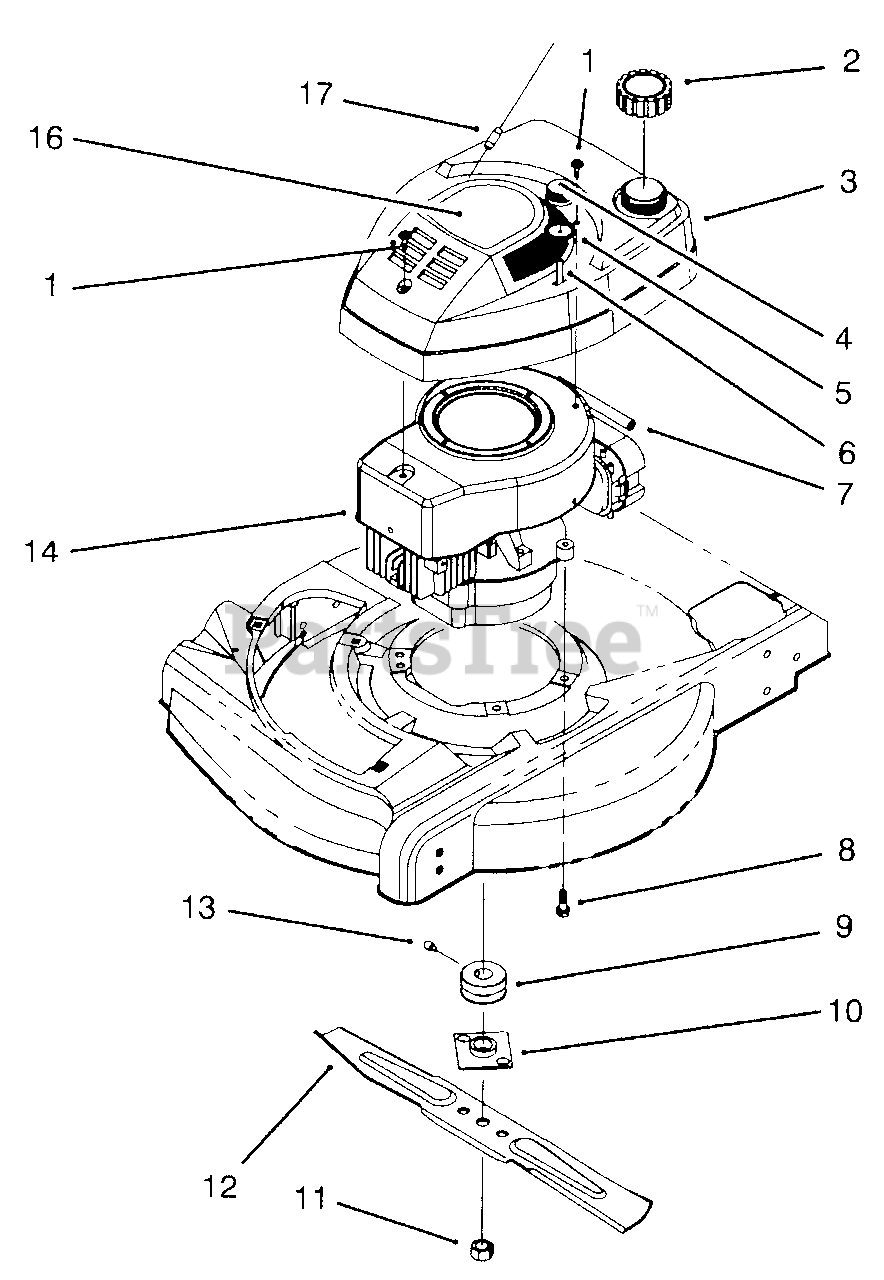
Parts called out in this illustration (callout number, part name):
1	Screw-Sems
2	Cap-Gas
3	Shroud-Tank
4	Bulb-Primer
5	Body-Primer
6	Hose-Primer
7	Line-Gas
8	Screw-Engine
9	Pulley-Engine
10	Plate & Collar
11	Nut-Blade
12	Blade-21 "
13	Screw-Set
14	Engine
16	Decal-Shroud
17	Rope-Stop
